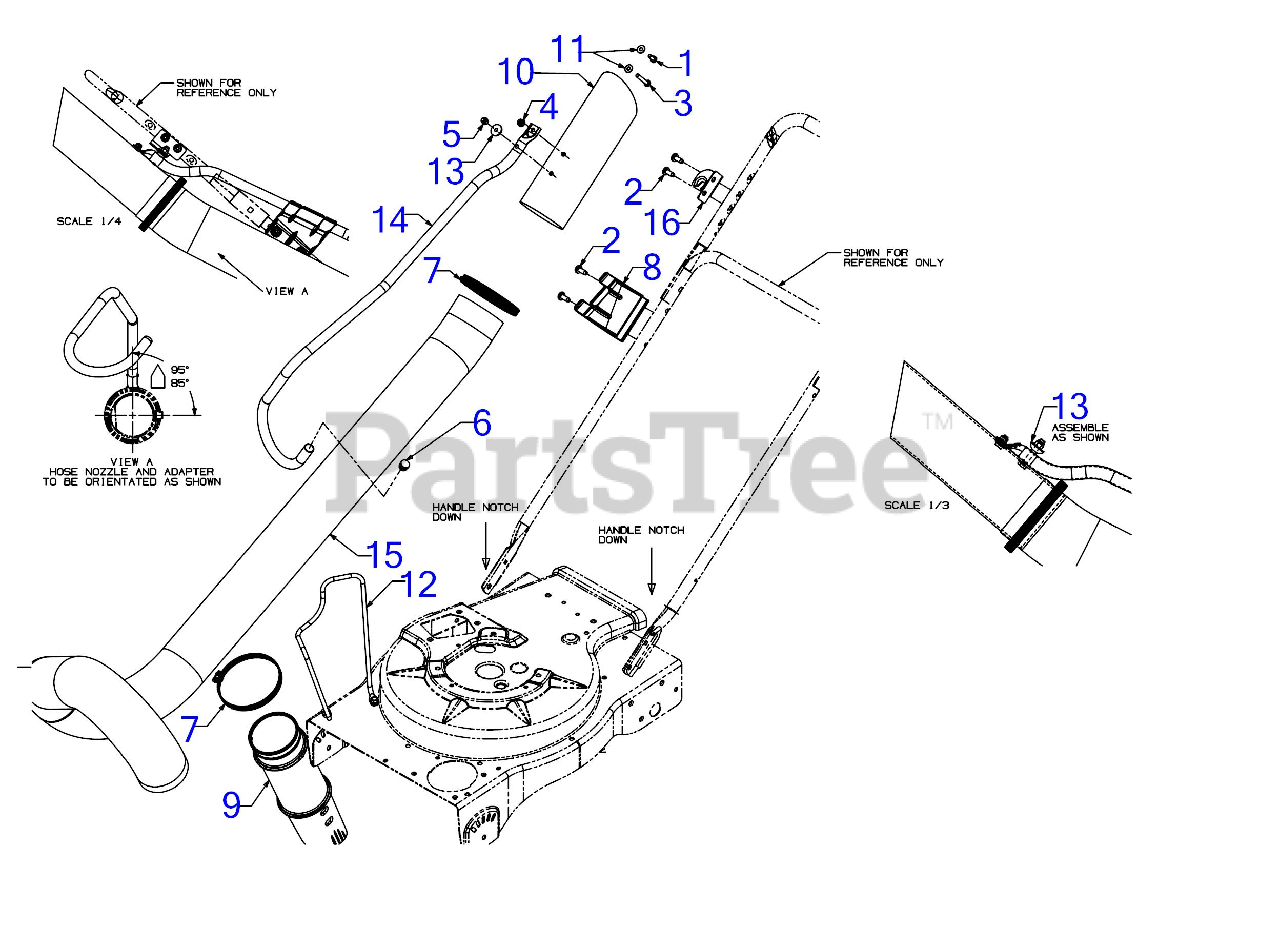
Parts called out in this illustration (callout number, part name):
1	SCREW 1/4-20 x .620 GR5
2	SCREW 5/16-18 x .750
3	BOLT 1/4-20X1.62 GR5
4	FLANGE LOCK NUT
5	HEX ACORN NUT
6	HANDLE PLUG
7	HOSE CLAMP
8	CLIP-HANDLE NOZZ
9	VAC HOSE ADAPTER
10	HOSE NOZZLE 3.875
11	FLAT WASHER .271:.630:.065
12	HOLDER ROD
13	HOSE HANGER SPACER
15	VACUUM HOSE 4.0 x 75.0
16	UPPER HANDLE BRACKET
